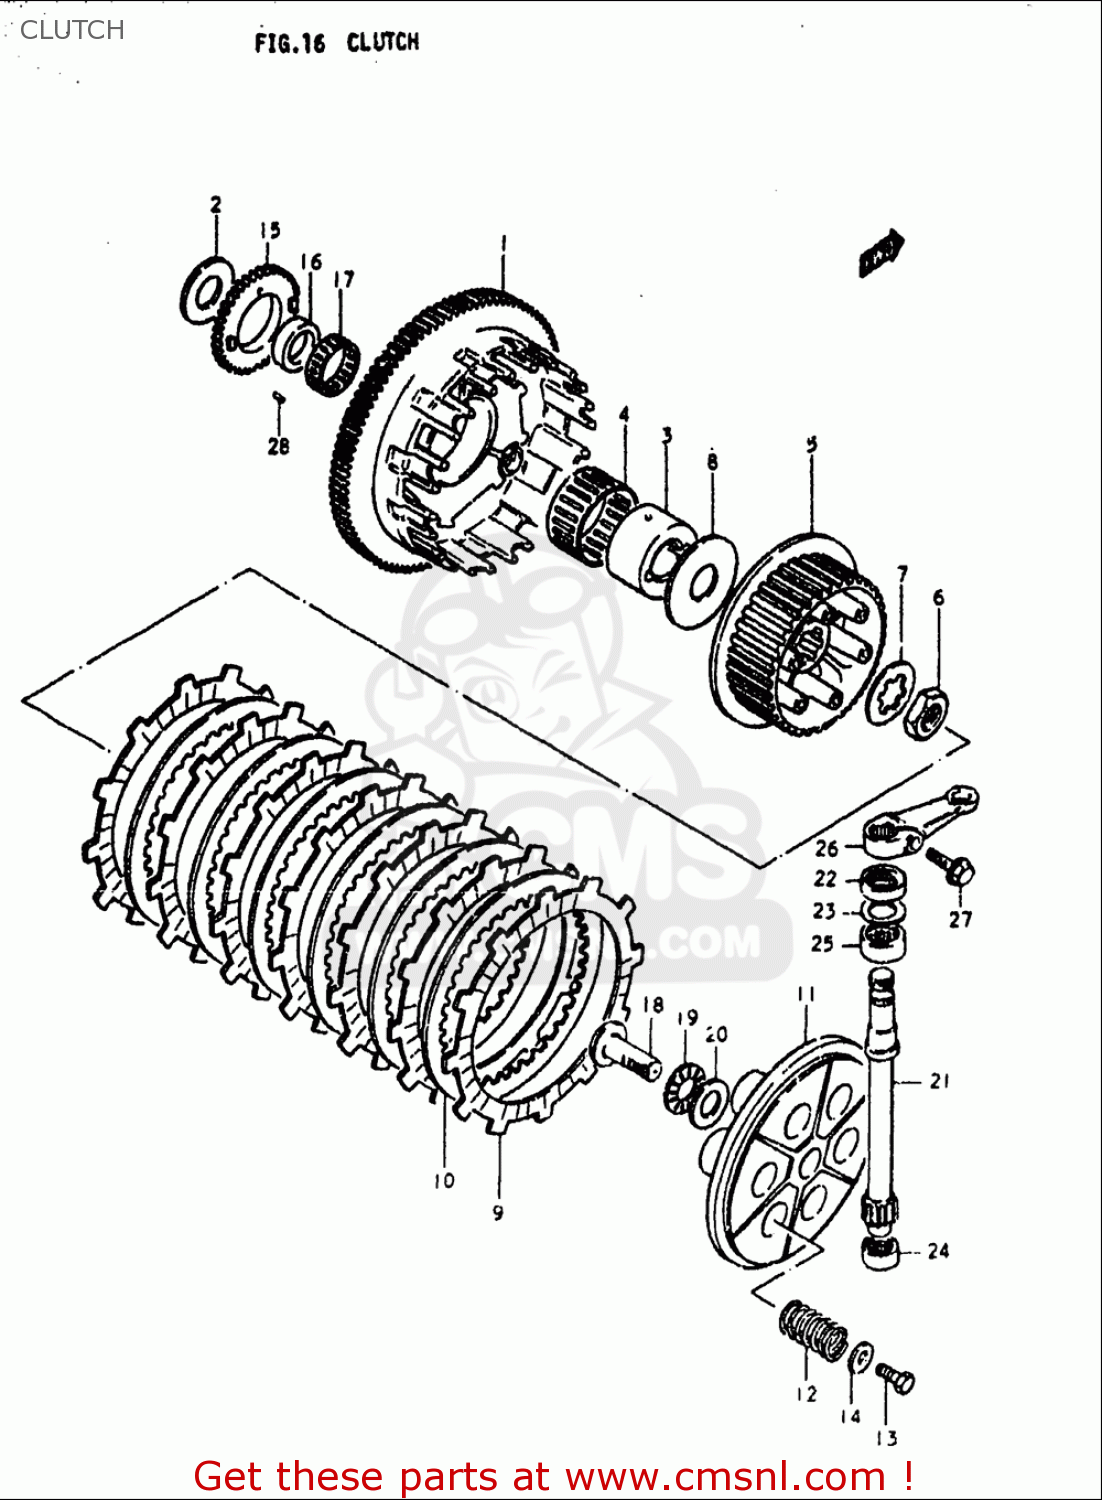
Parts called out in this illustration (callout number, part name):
1	GEAR ASSEMBLY,PRIMARY DRIVE
2	WASHER(25X50X2.5)
3	SPACER
4	BEARING(51X56X28)
5	HUB SET,CLUTCH SLEEVE
6	NUT
7	WASHER,LOCK
8	WASHER(25X66X3.5)
9	PLATE,CLUTCH DRIVE (NAS)
10	PLATE,CLUTCH DRIVEN NO.1 (NAS)
11	DISC,CLUTCH PRESSURE
12	SPRING
13	BOLT
14	WASHER(6.5X20X1.6)
15	GEAR,ENG OIL PUMP DRIVE(NT:34)
16	SPACER,OIL PUMP DRIVE GEAR
17	BEARING(36X40X10)
18	RACK,CLUTCH RELEASE
19	BEARING(15X28X2)
20	WASHER(15.5X28X1)
22	SEAL,OIL (12X22X9)
23	WASHER(14.5X22X1)
24	BEARING(12X19X12)
25	BEARING(15X22X12)
26	ARM,CLUTCH RELEASE
27	BOLT
28	CUSHION,PRIMARY DRIVEN GEAR
